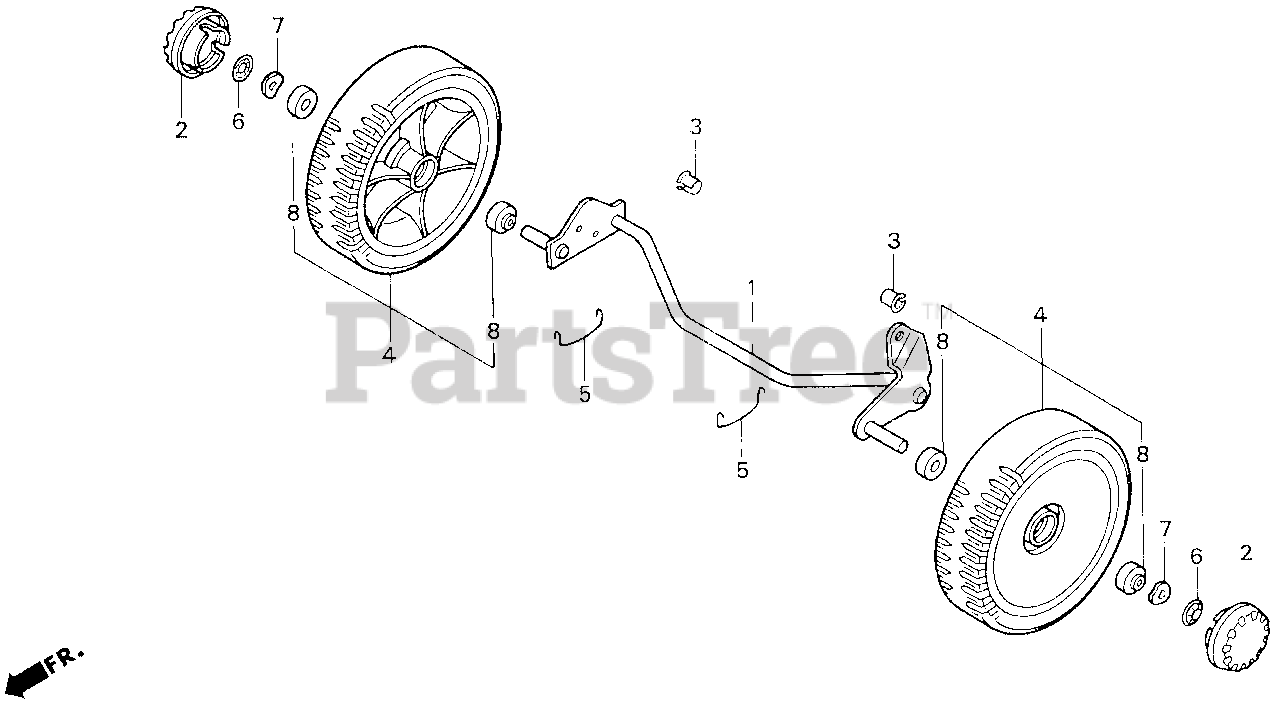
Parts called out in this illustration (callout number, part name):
1	SHAFT, FR. AXLE
2	CAP, WHEEL
3	BUSH, FR. AXLE SHAFT
4	WHEEL (200X45)
5	SPRING, SHAFT HOLDER
6	NUT, PUSH (12.7MM)
7	WASHER, SPRING
8	BEARING, RADIAL BALL
